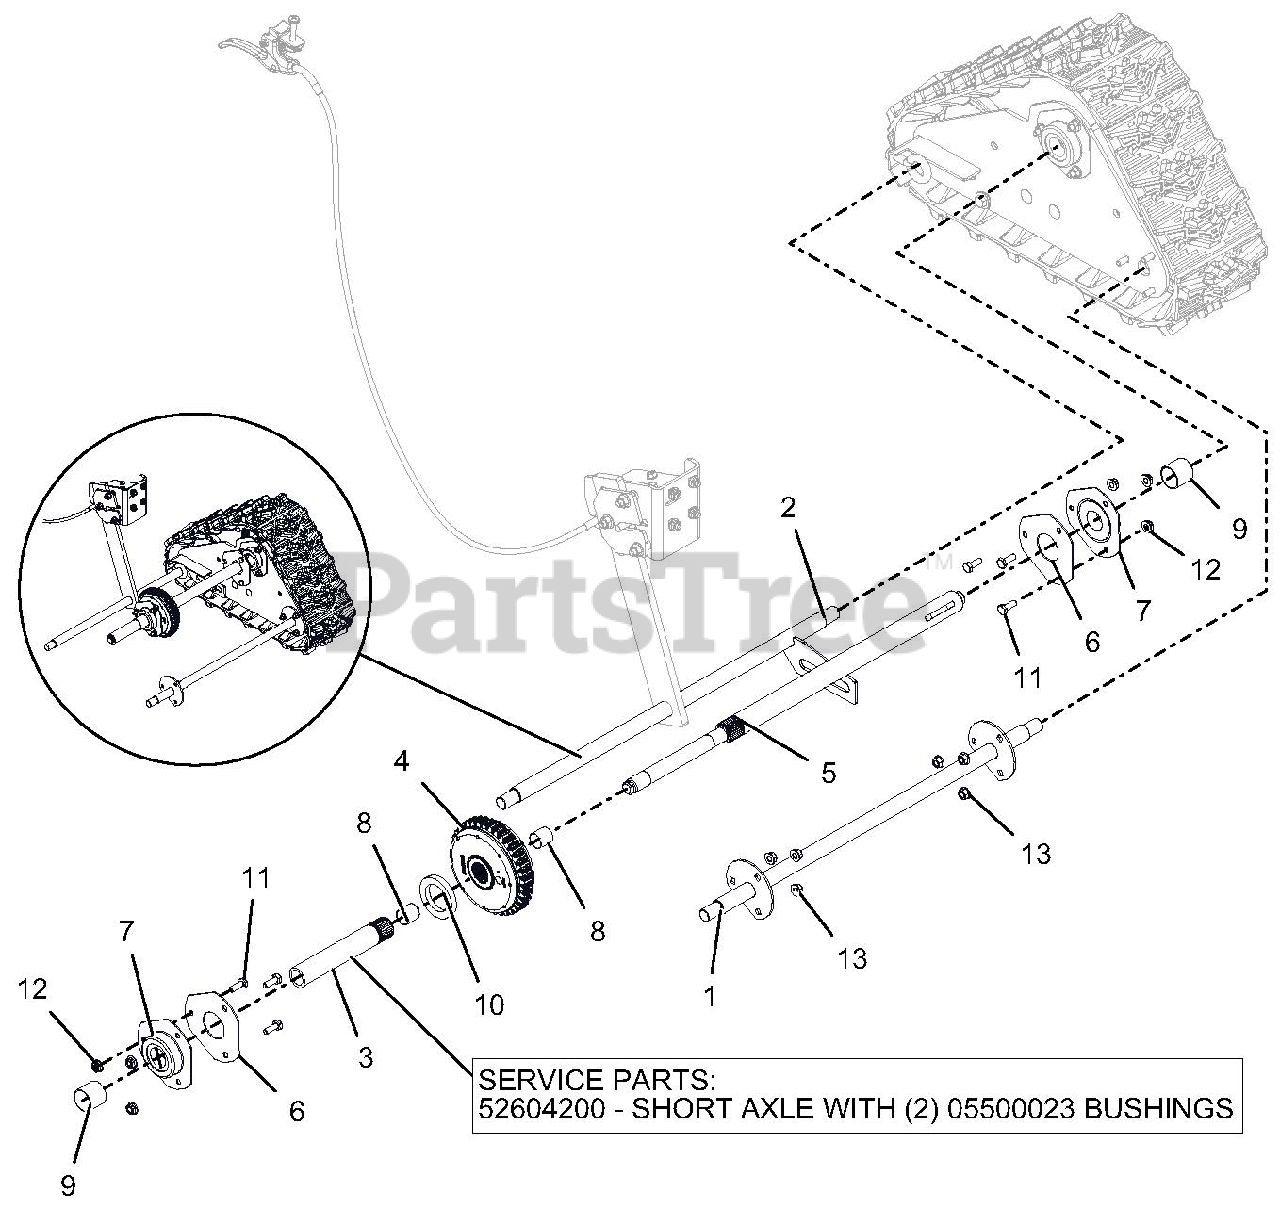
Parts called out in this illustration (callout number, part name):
1	AXLE, FRONT - PRO
2	AXLE, REAR - PRO TRACK
3	AXLE, SHORT-TRACK DIFFERENTIAL
3	AXLE, SHORT-TRACK W/BUSHINGS
3	BSHG-SLV .706X.764X.75 BRZ
4	DIFFERENTIAL, AUTOMATIC
5	AXLE, LONG-PRO AUTO DIFF
6	PLATE, BEARING SPACER
7	BRG-FLG 1.003/1.000 3 BOLT
8	BSHG-SLV .706X.764X.75 BRZ
9	BSHG-SLV, 1.012X1.125X1.00
10	WSHR-FL-NY 1.38X2.00X.25
11	@BLT-HEX .25-20X.75 GR5 YWZC
12	@NUT-LK-CTR-FLG .25-20 YWZC
13	@NUT-LK-TOP-FLG .25-20 YWZC
